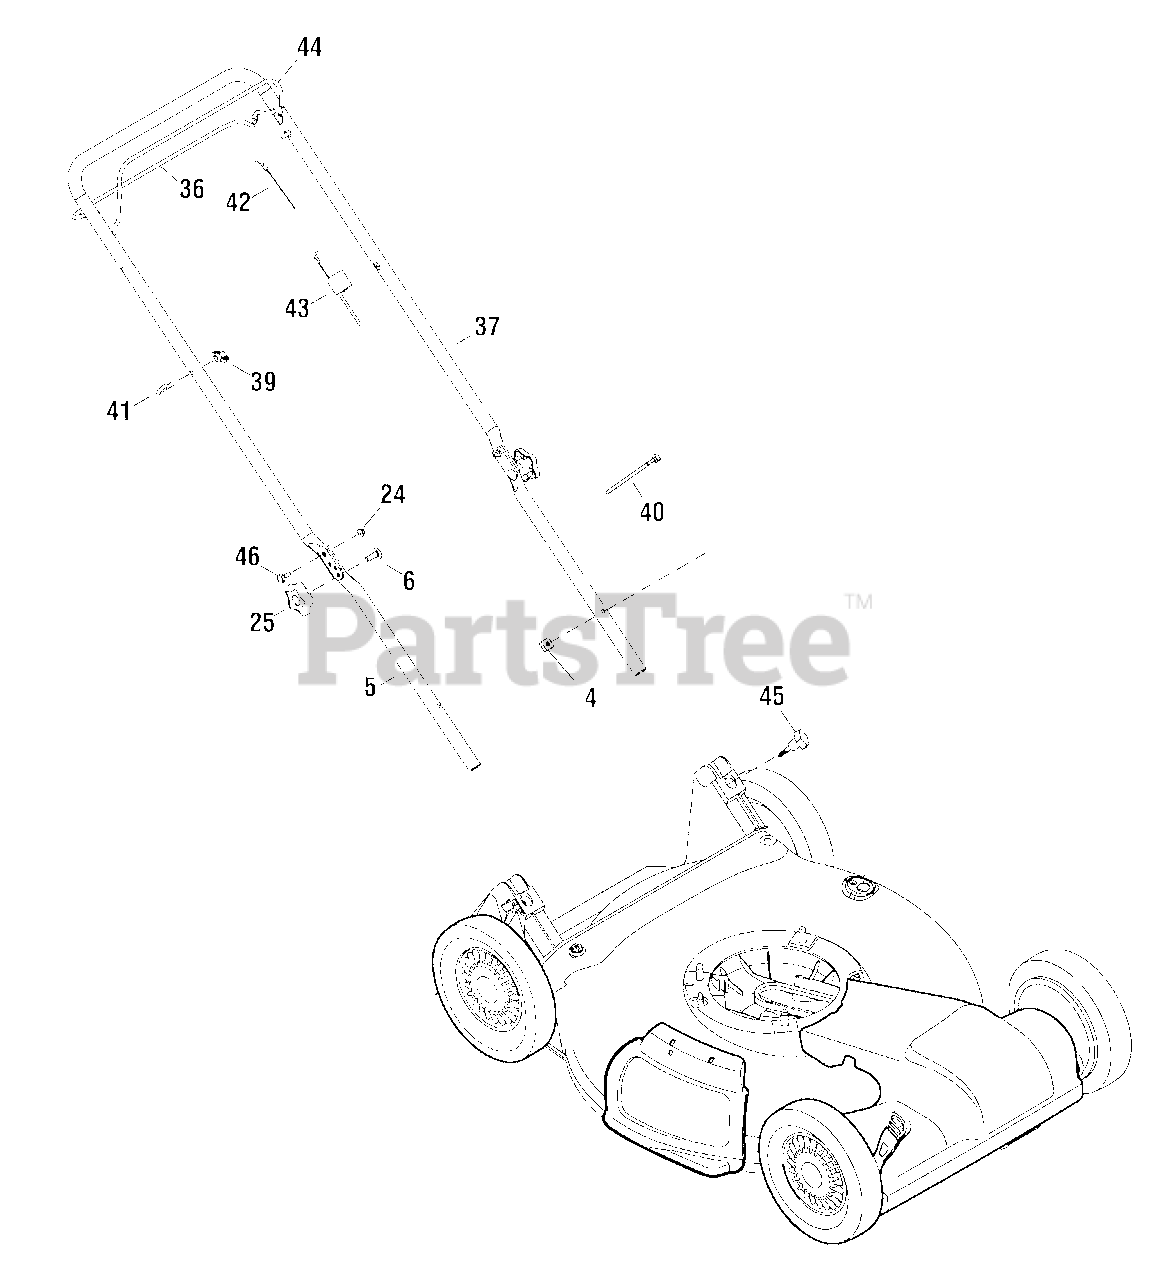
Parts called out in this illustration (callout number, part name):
4	NUT, Square, 1/4-20
5	HANDLE, Lower
6	BOLT, Carriage, 5/16-18 x 1, GR5
24	NUT, Nylock Flanged, 1/4-20
25	KNOB, Wing, 5/16-18
36	BAIL, Drive Control
37	HANDLE, Upper, Adjustable
39	KNOB, 1/4-20
40	TIE, Self Lock
41	GUIDE, Rope
42	CABLE, Control
43	CABLE, Drive
44	BAIL, Blade Control
45	NUT, Wing
46	BOLT, Shoulder, 1/4-20
